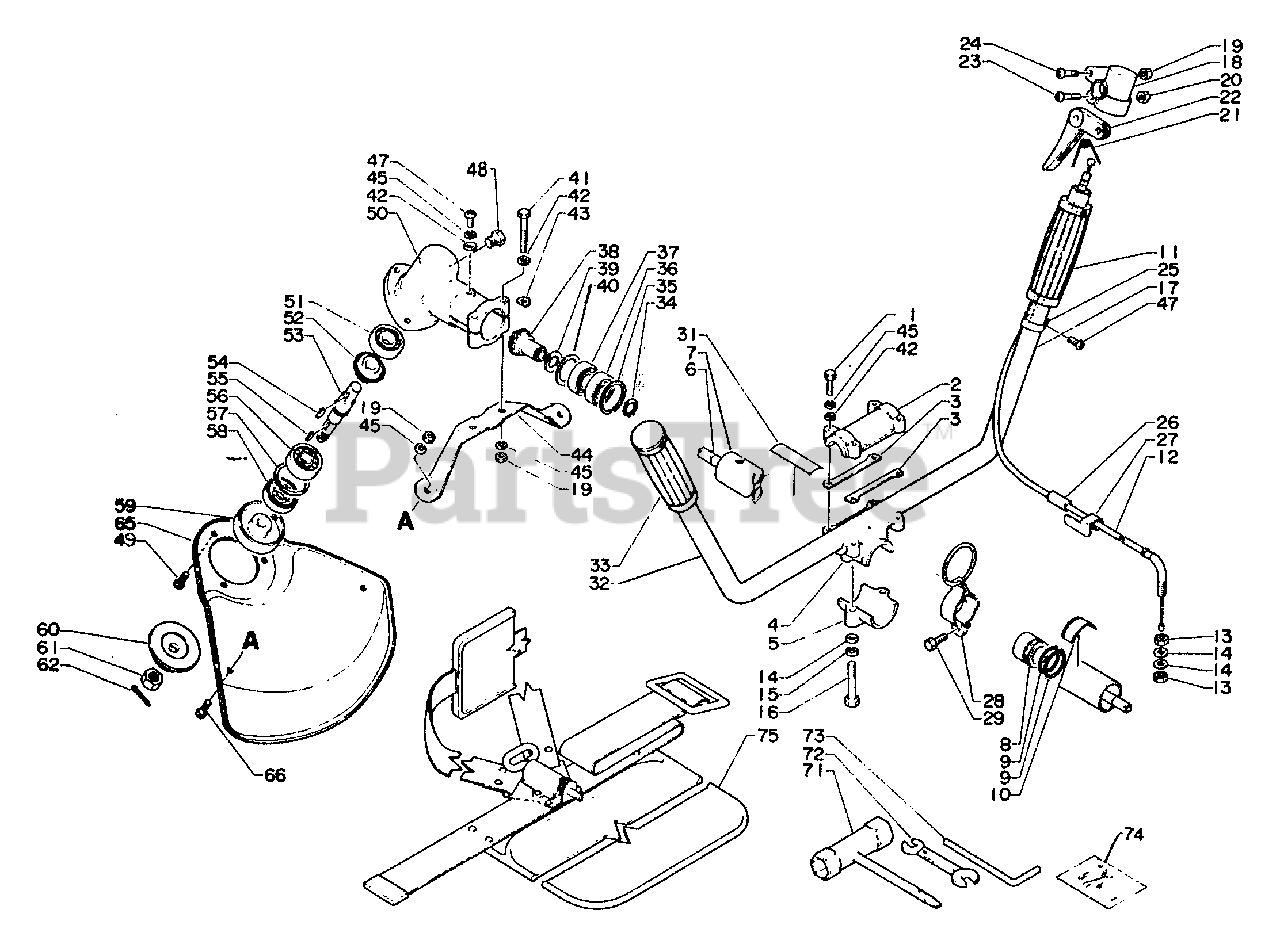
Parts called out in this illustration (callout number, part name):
1	BOLT - 5×25
6	DRIVESHAFT
7	MAIN PIPE ASSY
8	STOPPER
9	O-RING 22
10	LABEL - ALIGNMENT
11	GRIP, HANDLE
12	CABLE, THROTTLE
14	WASHER 6.5×11.5×0.8
15	WASHER, SPRING 6
16	BOLT - 6×30
18	BRACKET, TRIGGER
19	LOCKNUT - 5
20	NUT M5
22	TRIGGER, THROTTLE
23	SCREW 5×25
26	TUBE
28	HANGER KIT
29	BOLT 5×12
31	LABEL
32	HANDLE, LEFT
33	GRIP, HANDLE
34	RING, RETAINING - 12
35	RING, SNAP 28
36	BEARING, BALL 6001
37	BEARING, BALL 6001
38	GEAR SET
41	BOLT 5×40
42	WASHER, FLAT 5.5×10×0.8
44	BRACKET, SHIELD
45	WASHER, SPRING 5
47	SCREW 5×10
48	BOLT 8×8 SP
49	SCREW 5×10
50	CASE, GEAR
51	BEARING, BALL 6000
52	GEAR SET
53	DRIVESHAFT
56	BEARING, BALL - 6201 C3
57	RING, SNAP Ø32
58	SEAL, OIL
59	PLATE, ADAPTER - UPPER
60	PLATE, ADAPTOR - LOWER
62	PIN, COTTER 2×22
65	SHIELD
66	SCREW 5×8
71	T-WRENCH
72	SPANNER 8×10
73	TOOL, LOCKING 5×120 MM
74	PIN, COTTER 2×22 (PKG. OF 10)
75	SHOULDER STRAP ASSY
